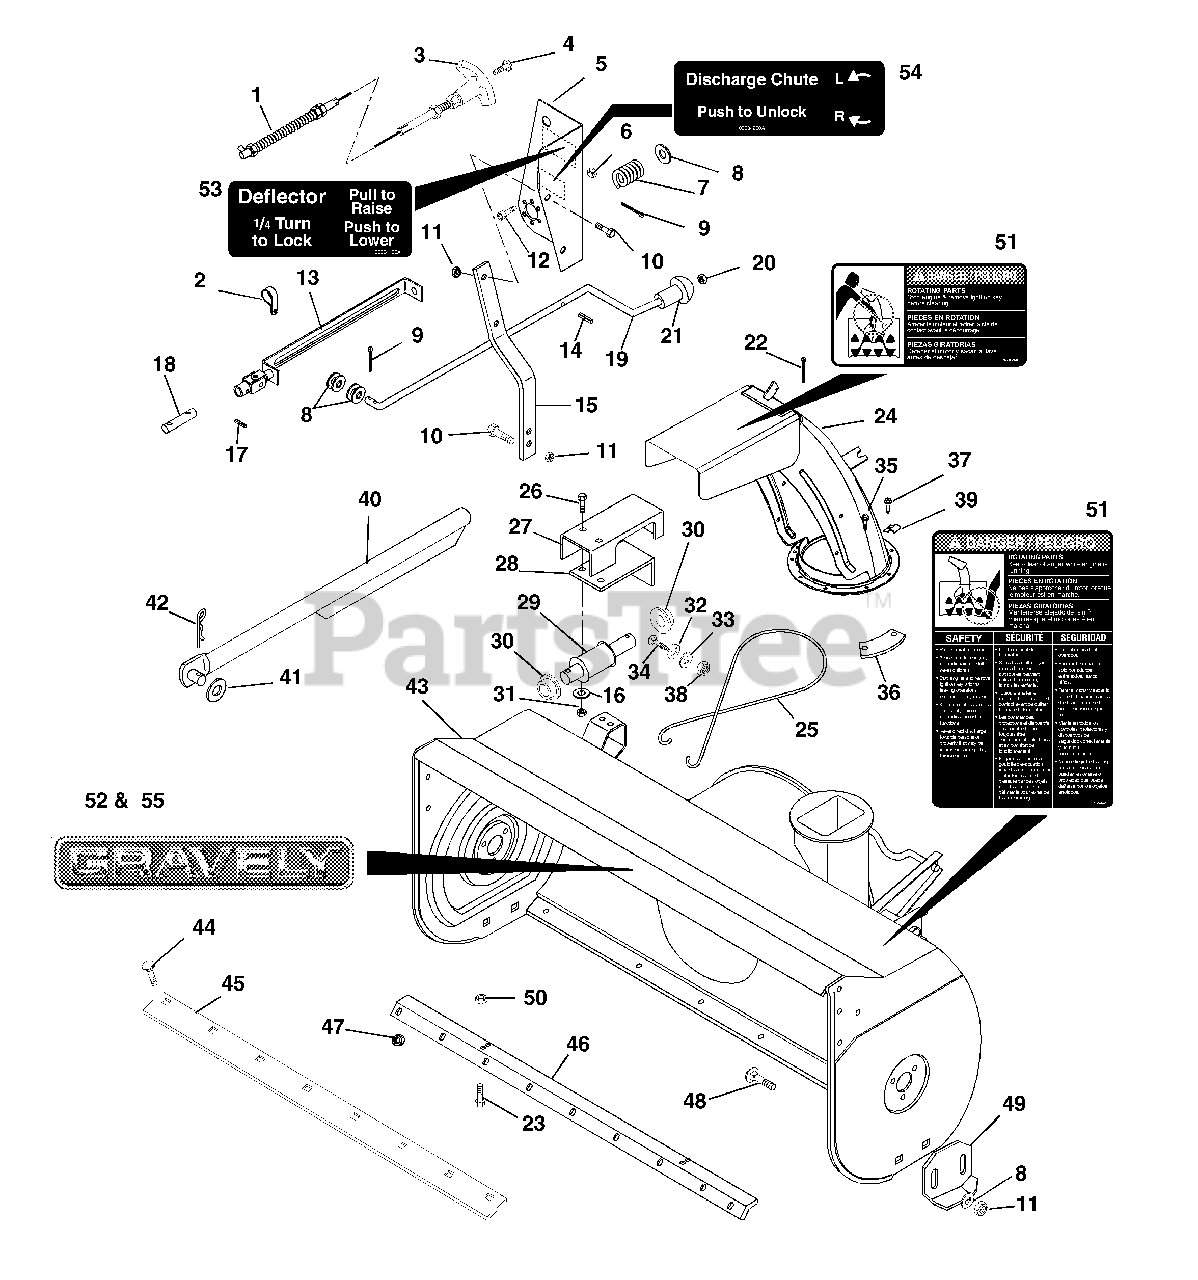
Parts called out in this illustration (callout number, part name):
1	Control Cable
2	Cable Clamp
3	Knob-Black
4	Screw-Machine 8-32 x .75
5	Control Bracket
6	Nut-Locking Dual Face 10-24
7	Spring-Compression
8	Washer-Flat-Steel .406 x .812 x .065
9	Pin-Cotter .06 x .75
10	Bolt-Hex .38-16 x 1.00 Grade 5
11	Nut-Locking-Center .38-16
12	Screw-Socket Head 10-24 x .38
13	Slotted Bracket
14	Pin-Roll .125 x 1.25 (006-S/N 000913 & up, 005-S/N 000351 & up)
14	Pin-Roll .187 x 1.500 (006-S/N 000101-000912, 005-S/N 000101-000350)
15	Bracket, Bar Crank
16	Pin-Roll .187 x 1.000
17	Pin-Roll .125 x .750
18	Connector Rod
19	Rod-Control (006-S/N 000913 & up)
19	Service Kit (006-S/N 000101-000912, 005-S/N 000101 & up)
20	Cap 3/8" Rod
21	Knob
22	Pin-Cotter .09 x .75
23	Bolt-Hex .38-16 x .75 Grade 5
24	Discharge Chute with Cap & Decal
25	Cable
26	Bolt-Hex .25-20 x .75 Grade 5
28	Spool Bracket
30	Bushing-Flange .76 x 1.0 x .580 x 1.48
31	Nut-Locking-Center .250-20
32	Washer-Lock .313 x .062
33	Washer-Flat .281 x .625 x .065
34	Bolt-Round Head Square Neck .25-20 x .62
35	Screw-Tapping 12-24 x .500 Torx Head
36	Chute Clamp
37	Screw-Tapping 12-24 x .75 Torx Head
38	Nut-Hex .250-20 Grade 2
39	Cable Clamp
40	Rod-Push Weldment
41	Washer-Flat-Steel .812 x 1.500 x .139
42	Pin-Hair Cotter Internal .15 x 2.937
43	40" Blower Housing (005-S/N 000437 & up)
43	40" Blower Housing (005-S/N 000101-000436)
43	48" Blower Housing (006-S/N 001131 & up)
43	48" Blower Housing (006-S/N 000101-001130)
44	Bolt-Round Head Square Neck .31-18 x 1.00
45	Scraper Blade 48"(006)
45	Scraper Blade 40"(005)
46	Scraper Blade Brace (006)
46	Scraper Blade Brace (005)
47	Nut-Locking-Center .31-18 (005)
47	Nut-Locking-Center .31-18 (006)
48	Bolt-Round Head Square Neck .38-16 x 1.00
49	Runner-Skid Shoe (005-S/N 000437 & up, 006-S/N 001131 & up)
49	Runner-Skid Shoe (005-S/N 000101-000436, 006-S/N 000101-001130)
50	Nut-Locking Top .375-16
51	Decal-Danger-Set
52	Decal, Gravely Logo
53	Deflector Decal
54	Chute Crank Decal
55	Decal, 15" Gravely Logo-Krinkle Black
